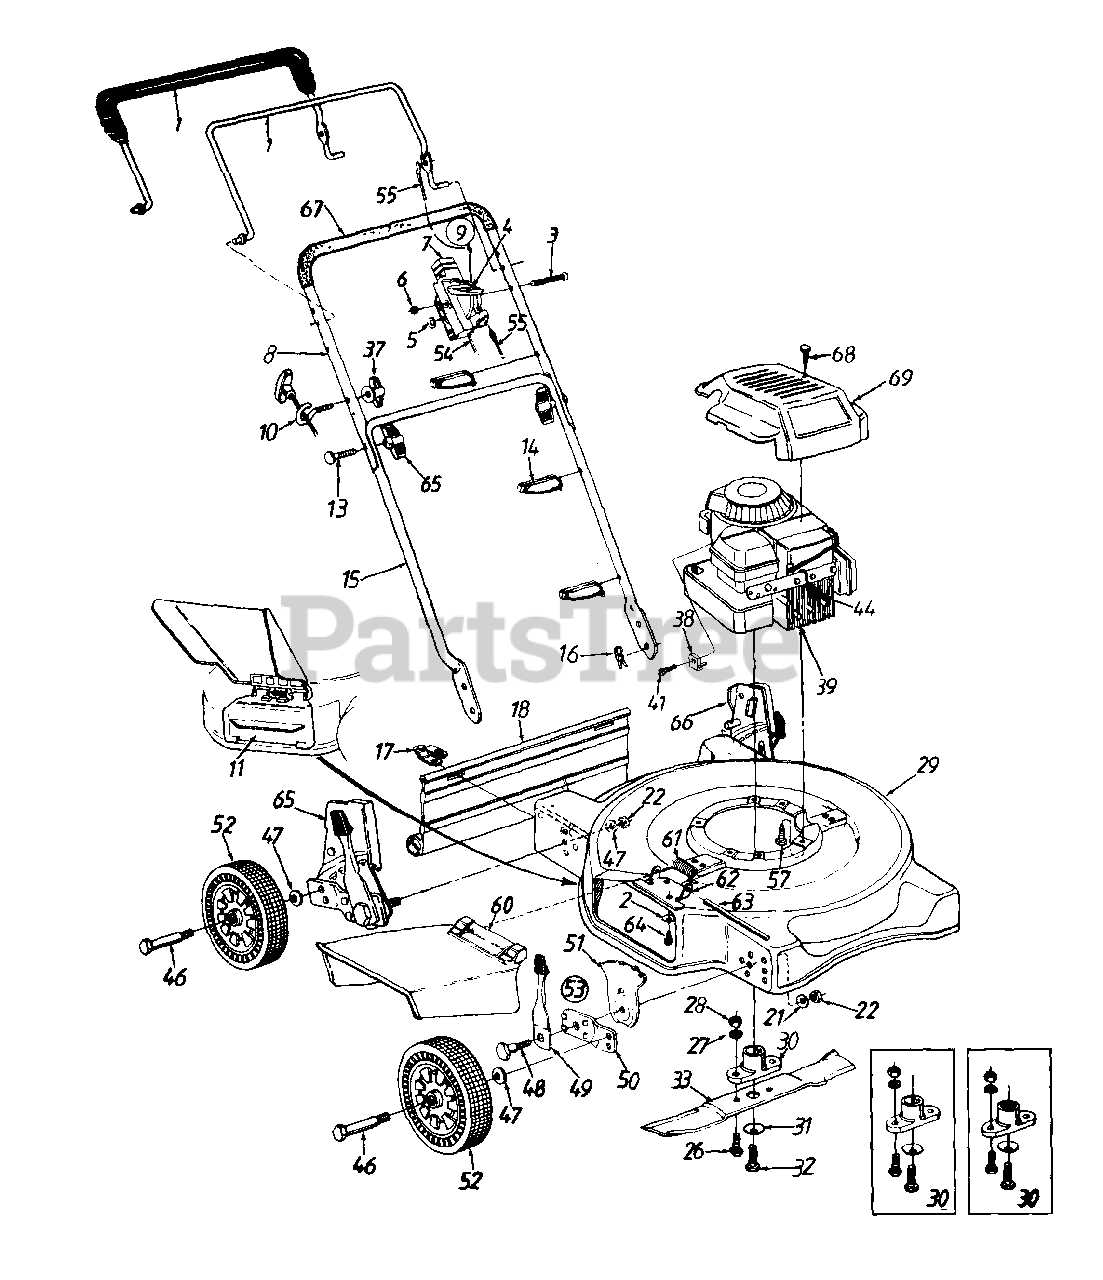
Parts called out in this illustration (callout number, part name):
2	Bell-Wash. 1/4" I.D.
3	Oval C-Sunk Mach. Scr.
4	Throttle Lever
5	Spr. Wash .66" I.D.
6	Hex L-Nut 1/4-20 Thd.
7	Throttle Body
10	Rope Guide
11	Mulching Plug
13	Curved Hd. Bolt 5/16-18 x 2" Lg
14	Cable Tie
16	Hairpin Cotter
17	Hinge Clip
18	Rear Flap (20")
22	Hex Nut 3/8-16 Thd.
26	Hex Bolt 3/8-24 x 1" Lg.
27	L-Wash. 3/8" I.D.
28	Hex Nut 3/8-24 Thd.
31	Bell-Wash .39" I.D.
32	Hex Bolt 3/8-24 x 1.5" Lg.
33	20" Blade
37	Wing Nut 1/4-20 Thd.
38	Cable Clamp (B&S)
39	Engine
41	Hex Wash. Hd. Tap Scr. #10-32 x .62" Lg. (B&S)
44	Spark Plug Boot
46	Axle Bolt
47	Bell-Wash .400" I.D. x .88"
48	Shld. Bolt .50" Dia. x .35"
49	Spring Lever Ass'y. w/Knob
51	Height Adj. Plate
52	Wheel Ass'y. Comp.
53	Height Adj. Ass'y. Comp.- R.F.
54	Throttle Cable - 51"
55	Control Cable - 39"
57	Hex L-Wash. Hd. Scr. 3/8-16 x 1.0" Lg.
60	Chute Deflector Ass'y.
61	Torsion Spring
62	Adapter Plate
63	Hinge Pin
64	Hex Self-Tap Scr. 1/4-20 x .5"
67	Foam Grip
68	Hi-Lo Scr. #10 x 1.25" Lg.
69	Black Shroud
